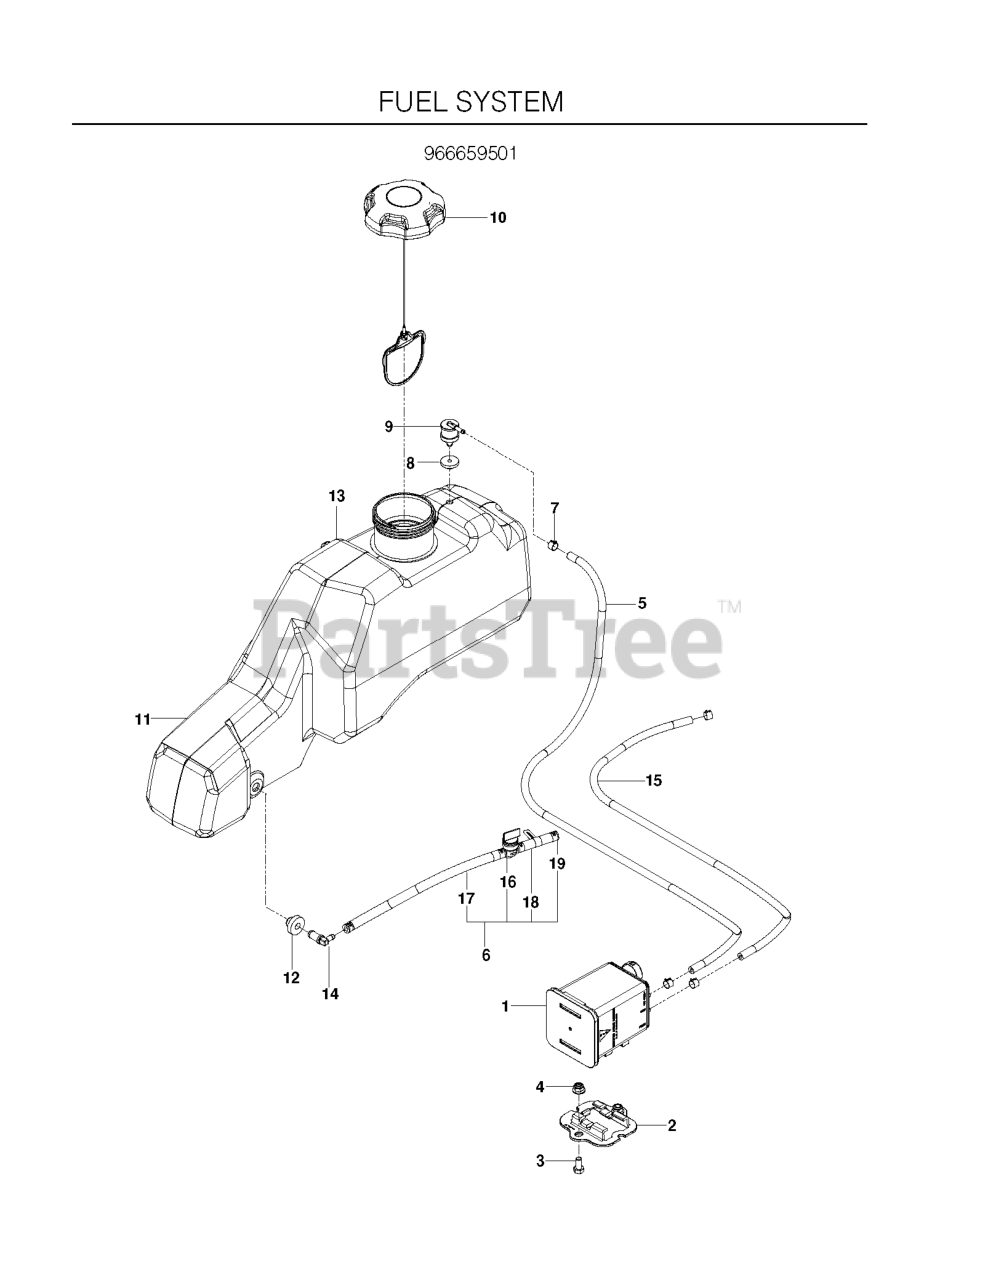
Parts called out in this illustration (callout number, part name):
1	CANNISTER, CARBON
2	BRACKET, CANISTER
3	HCS 5/16-18 X 5/8 GR 5 ZD
4	5/16-18 NYLOC FLANGE NUT
5	HOSE, VAPOR 3/16 X 39"
6	FUEL LINE ASSY
7	CLAMP, HOSE
8	GROMMET, CHECK VALVE
9	VALVE.FUEL.CHECK
10	CAP, FUEL
11	SHIELD, HEAT
12	RUBBER GROMMET
13	TANK, FUEL, RT-EPA
14	STEM, FUEL TANK
15	HOSE, FUEL, 3/16" X 20"
16	FUEL VALVE
17	GAS LINE 10"
18	FUEL LINE 3"
19	HOSE CLAMP
